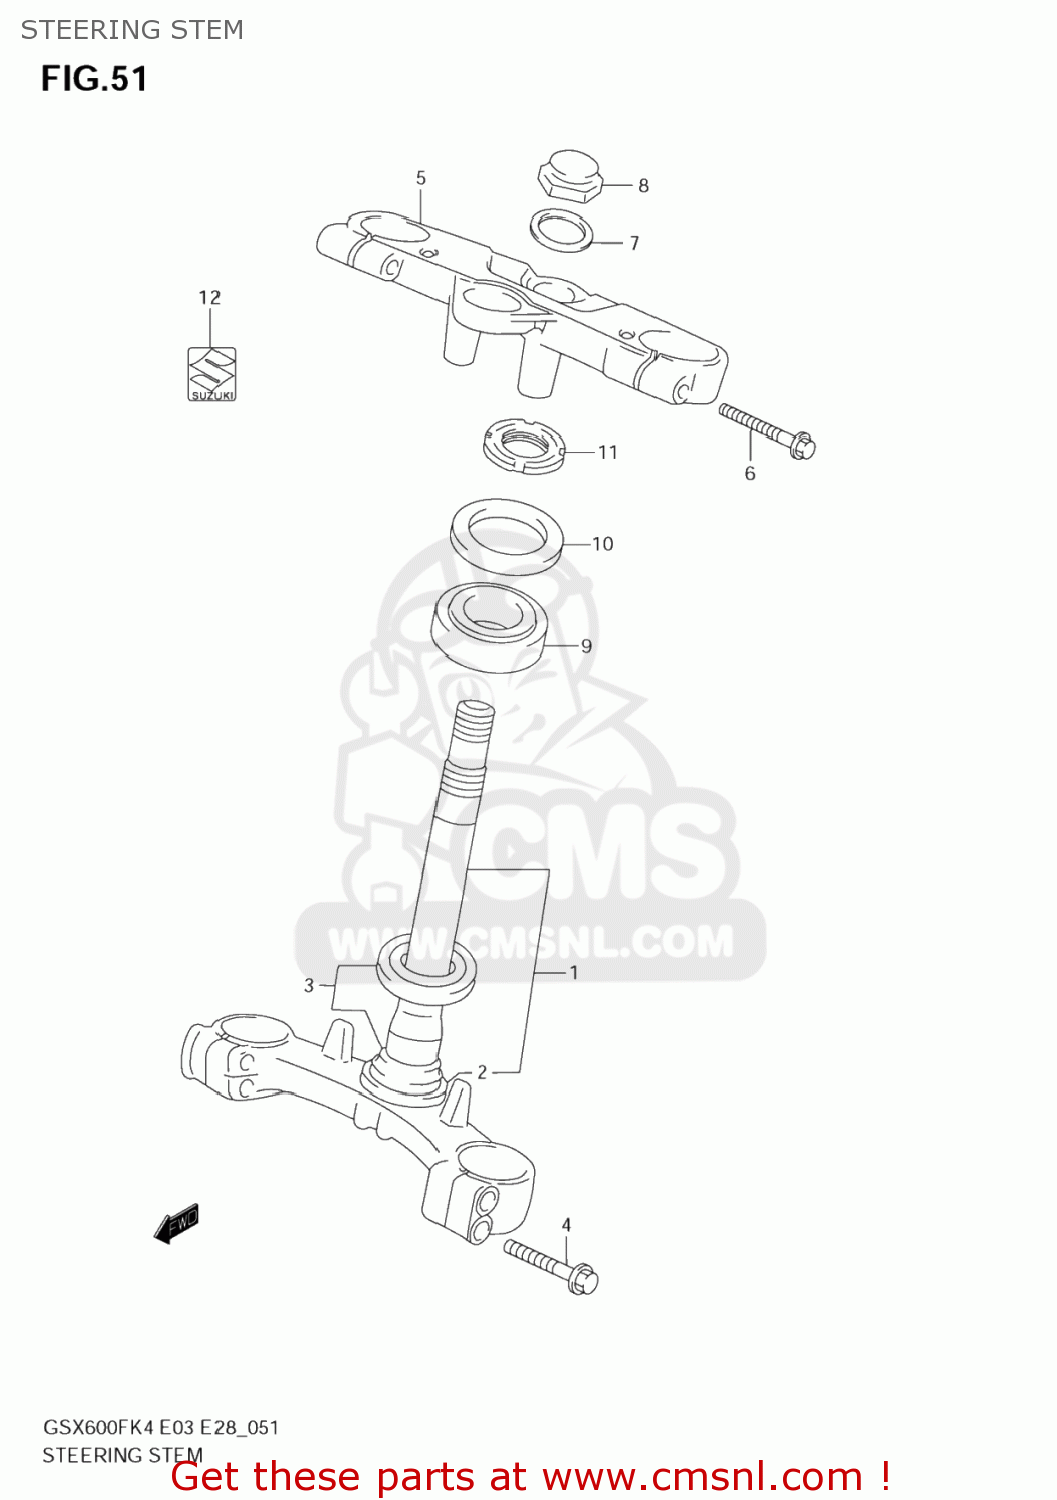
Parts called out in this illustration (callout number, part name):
1	STEM,STEERING
2	SEAL,STEERING LWR
3	BEARING(30X55X17)
4	BOLT
5	HEAD,STEERING STEM
6	BOLT
7	WASHER(22.5X32X1.6)
8	NUT,CAP
9	BEARING(25X47X15)
10	DUST SEAL,STEERING UPR
11	NUT,STEERING STEM(25X44X10)
12	EMBLEM,S
